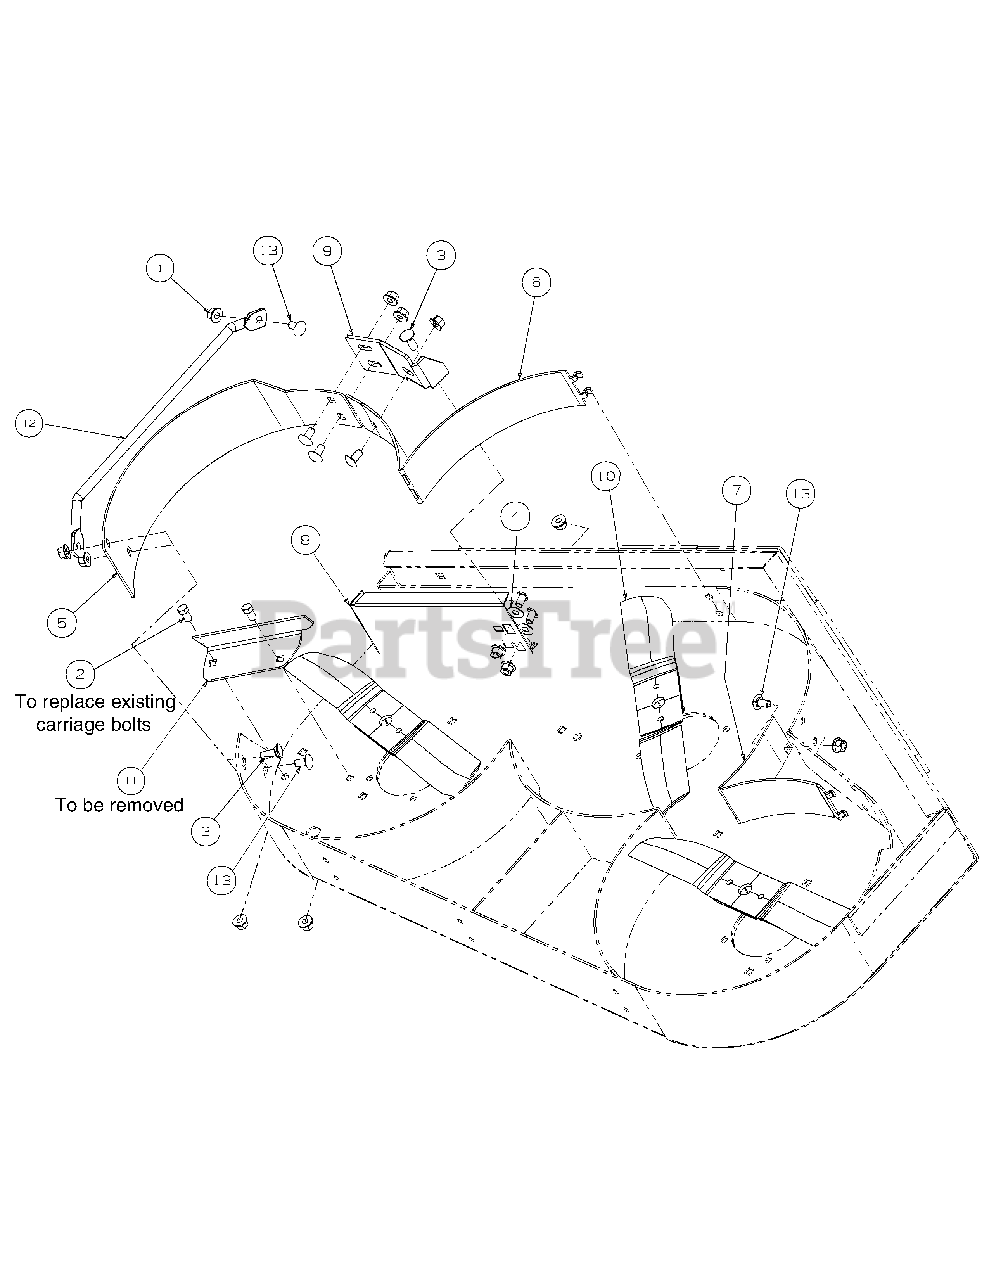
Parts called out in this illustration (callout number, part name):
1	Hex Nut, 3/8-16 Flange Lock
2	HHCS, 3/8-16 x .75
3	Carriage Bolt, 3/8-16 x 1.00
4	Push Retainer
5	Mulch Baffle, Discharge
6	Mulch Baffle
7	Mulch Baffle, Small
8	Mulch Plug Bracket
9	Mulch Bracket
10	Blade
11	Fabricated Deck, Chute Bracket
12	Fabricated Deck Finger Guard
13	Carriage Bolt, 3/8-16 x .75
